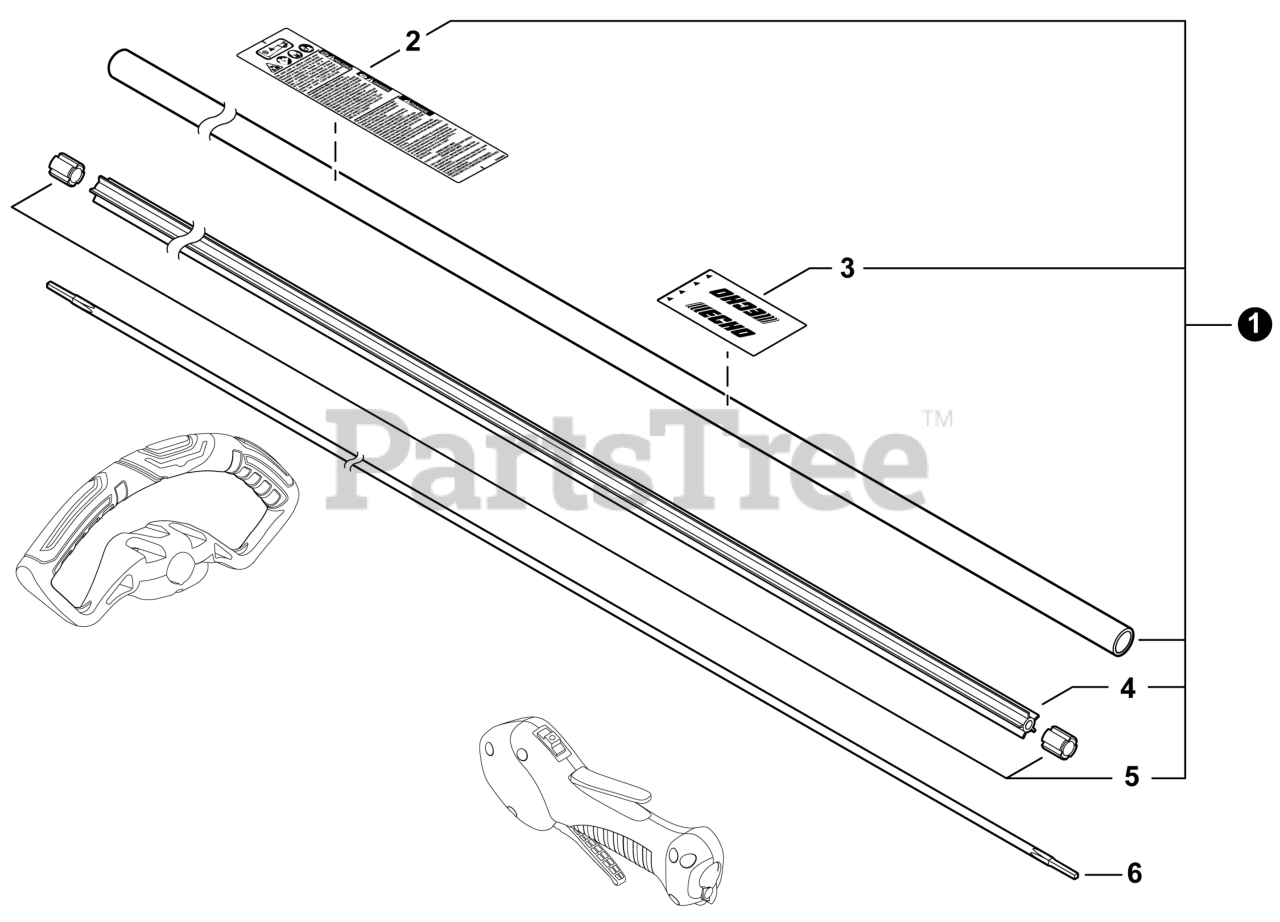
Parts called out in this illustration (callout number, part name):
1	MAIN PIPE ASSY
2	LABEL - CAUTION
3	LABEL - HANDLE LOCATION
4	LINER, FLEXIBLE 21.6x1420
6	DRIVESHAFT - FLEXIBLE
